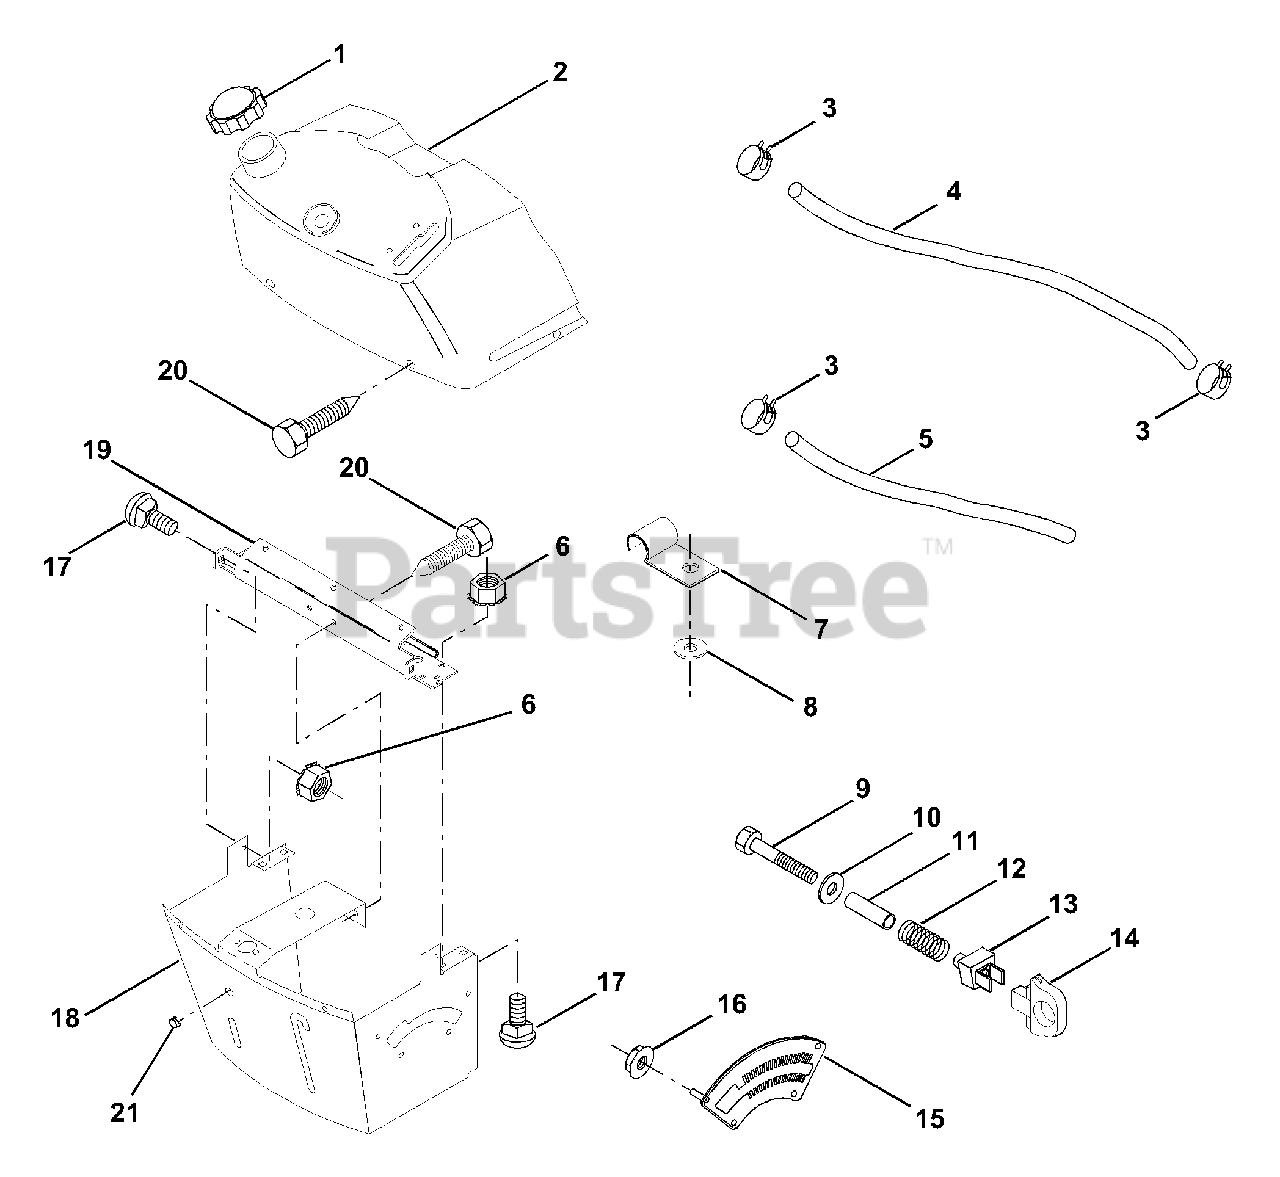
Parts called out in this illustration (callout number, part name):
2	Assembly, Dash & Fuel Tank
3	Clamp, Hose
4	Line, Fuel
5	Line, Fuel
6	Nut, Hex, Keps 1/4-20
7	Clip, Fuel Line
8	Washer 9/32 x 3/4 x 16 Ga.
9	Bolt, Hex, Fin 1/4-20 x 1-3/4
10	Washer 11/32 x 11/16 x 16 Ga.
11	Spacer, Split
13	Clip, Height Adjustment
14	Knob, Height Stop
15	Adjustment, Quadrant Height
16	Nut, Self-Threading 3/16-18
17	Bolt, Carriage 1/4-20 x 1/2 Gr. 5
18	Support Assembly, Dash
19	Brace, Cross
20	Screw, Self-Tapping 1/4-20 x 1/2
21	Plug Dome Black
